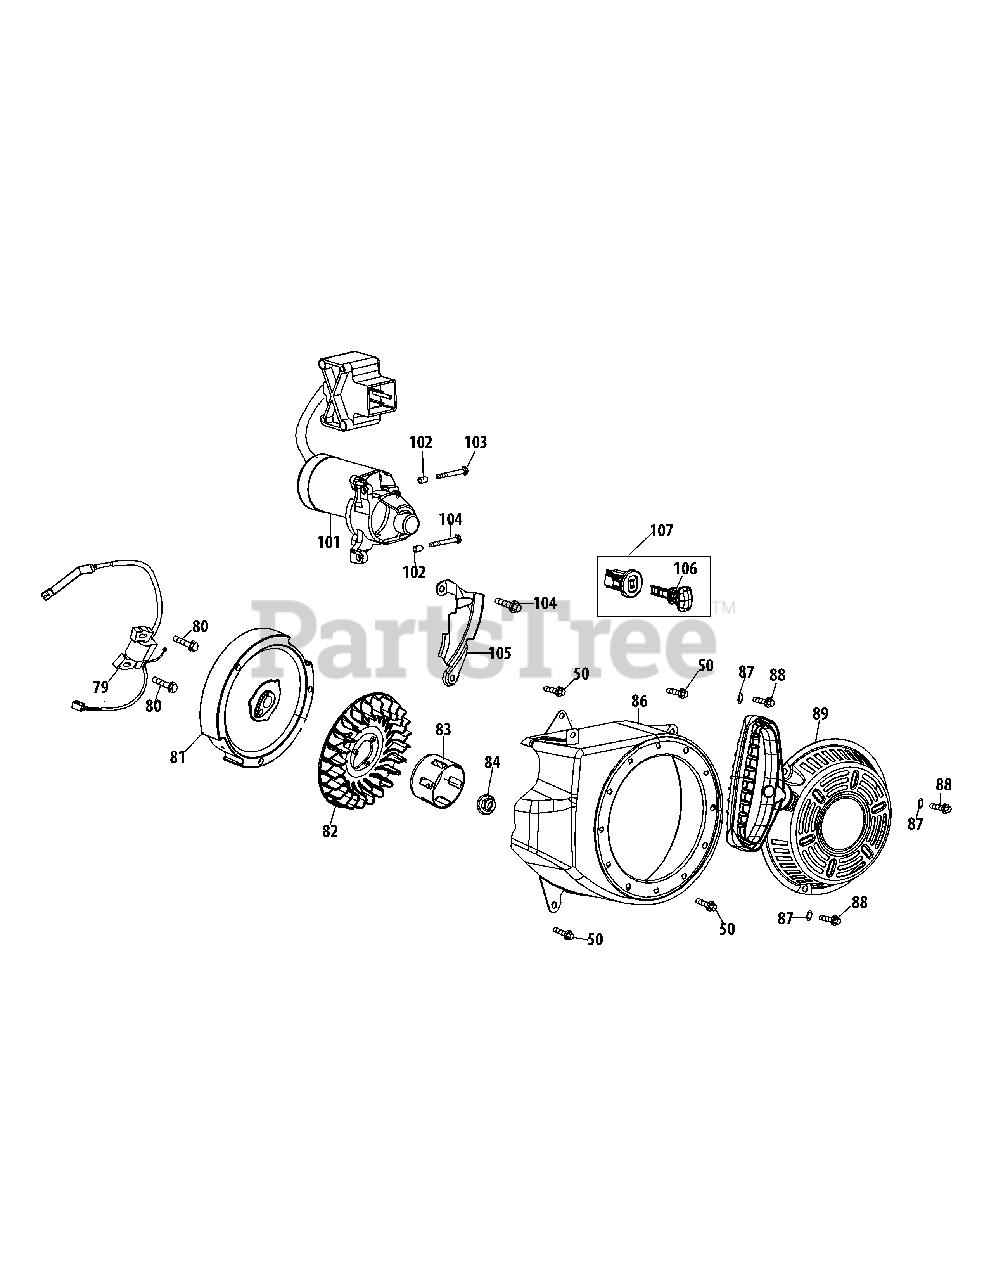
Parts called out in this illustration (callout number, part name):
50	Bolt:M6X12 Zinc
79	Ignition Coil
80	Flange Bolt M6X25
81	Flywheel
82	Cooling Fan
83	Starter Cup
84	Nut M14
86	Fan Cover Complete
87	Flat Washer
88	Flange Bolt
89	Recoil Starter Assembly
101	Electric Starter
102	Dowel Pin 8X8
103	Starter Bolt
104	Bolt:M6X12 Zinc
105	Blower Housing Shield
106	Key
107	Switch Assembly
